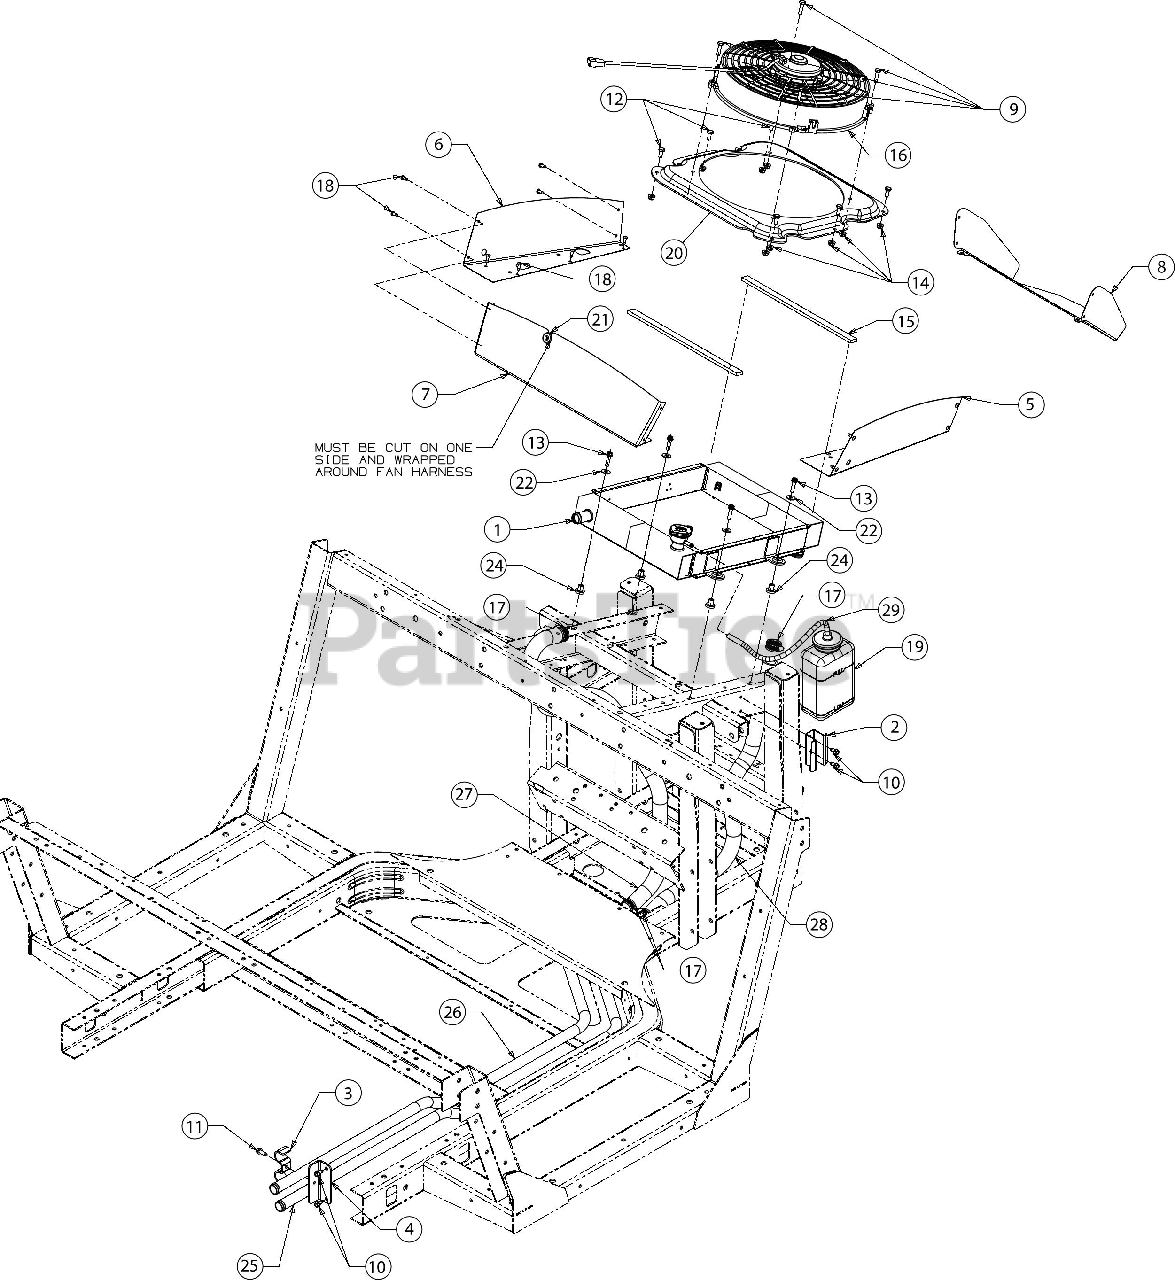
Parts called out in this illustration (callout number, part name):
1	RADIATOR ASSEMBLY
2	OVERFLOW BRACKET
3	UV TUBE BRACKET
4	RADIATOR HOSE BRACKET
5	SHROUD (4X4) (RH)
6	SHROUD (4X4) (LH)
7	SHROUD (4X4) (REAR)
8	SHROUD (4X4) (FRONT)
9	SCREW 1/4-20 X1.00 GR5
10	SCREW 1/4-20 X.500
11	SCREW 1/4-20 x .750
12	SCREW 1/4-20 x .620 GR5
13	SCREW 1/4-20 x 1.00
14	FLANGE LOCK NUT
15	FOAM TAPE .75" WIDE x .25" THICK
16	12V ELECTRIC FAN
17	HOSE CLAMP
18	POP RIVET
19	OVERFLOW TANK
22	FLAT WASHER .28 ID x .74 OD x .063
24	STEP SPACER
27	RADIATOR HOSE
28	RADIATOR HOSE
29	OVERFLOW TUBE
